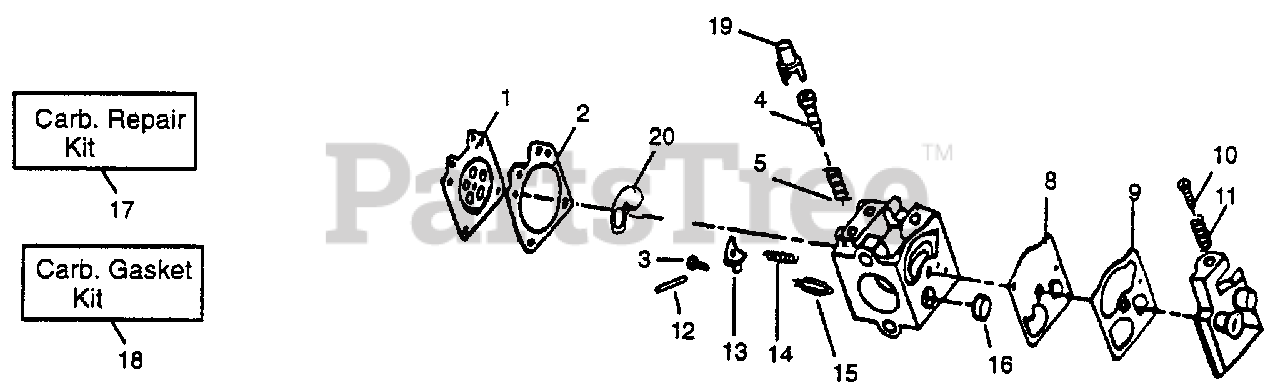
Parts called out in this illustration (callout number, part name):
1	Metering Diaphragm
2	Metering Diaphragm Gasket
3	Metering Lever Pin Screw
4	Mixture Needle
5	Mixture Needle Spring
8	Fuel Pump Diaphragm
9	Fuel Pump Gasket
10	Idle Speed Screw
11	Idle Screw Spring
12	Metering Lever Pin
13	Metering Lever
14	Metering Lever Spring
15	Inlet Needle Valve
16	Fuel Inlet Screen
17	Carb. Kwik Repair Kit
18	Carb. Gasket/Diaphragm Kit
19	Limiter Cap
20	Circuit Plate Gasket
